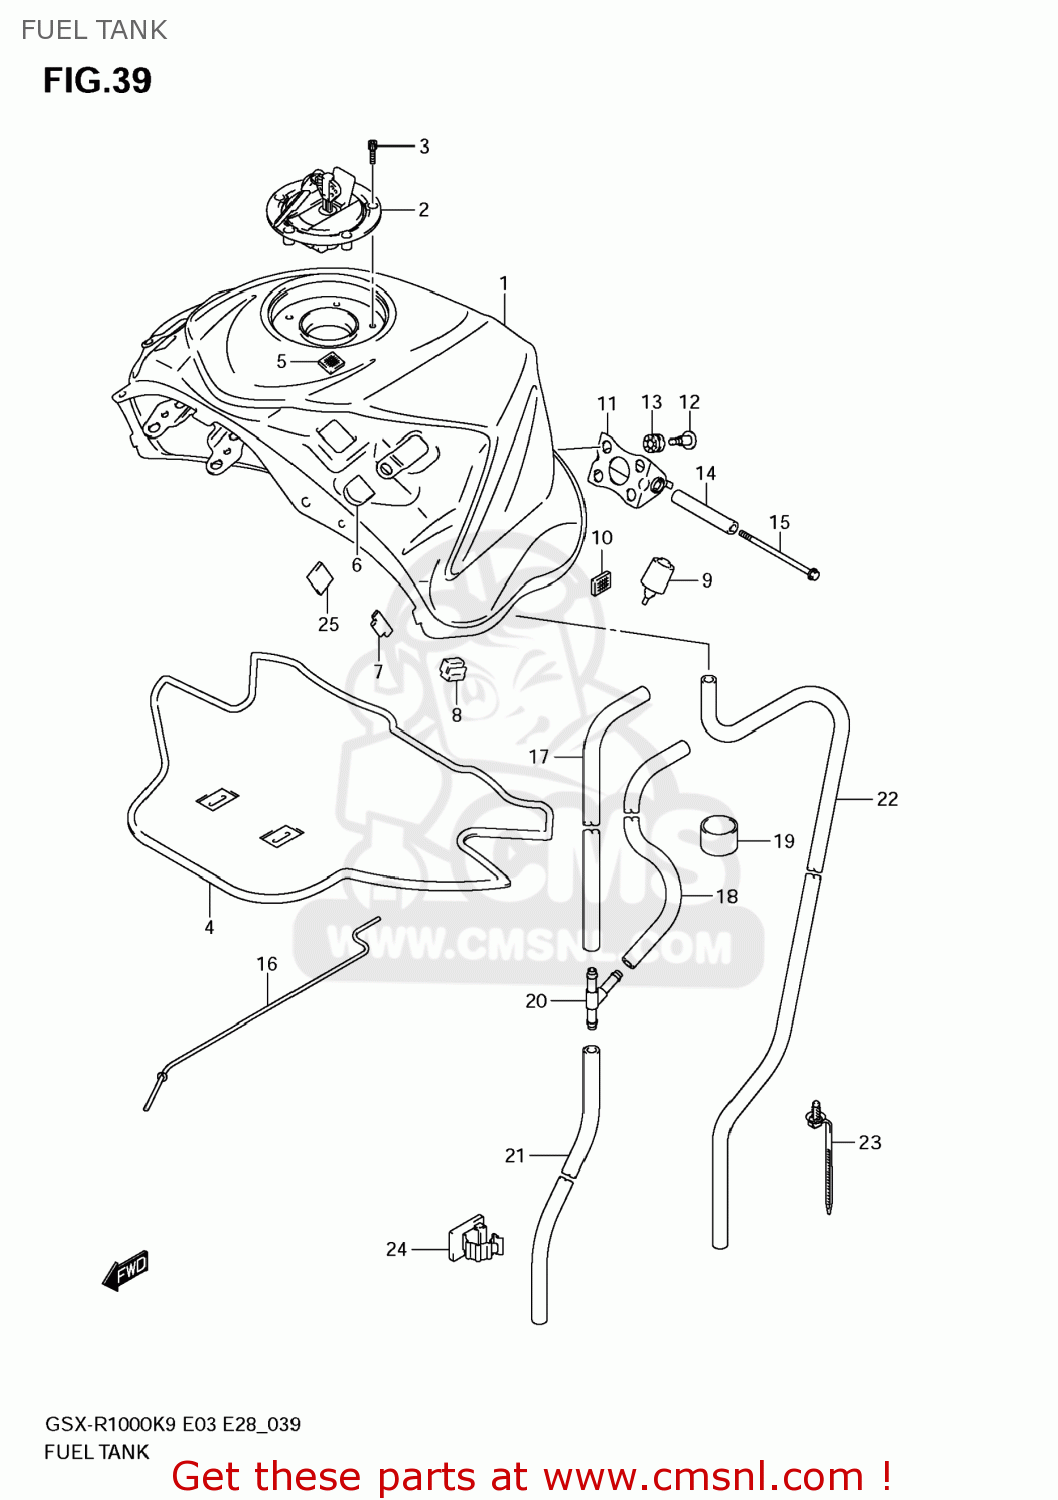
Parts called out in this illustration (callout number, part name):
1	TANK ASSY,FUEL
2	CAP SET,FUEL TANK
3	BOLT(5X20)
4	SHIELD,FUEL TANK HEAT
5	FASTENER
6	CUSHION
7	CUSHION,FUEL TANK COVER
8	CUSHION,FUEL TANK SIDE
9	CUSHION,FUEL TANK RR
10	FASTENER
11	BRACKET,FUEL TANK NO.1
12	SCREW,FUEL TAN
13	CUSHION
14	SPACER,FUEL TANK RR
15	BOLT(6X110)
16	STAY,FUEL TANK
17	HOSE,FUEL TANK BREATHER NO.1
18	HOSE,TANK BREATHER NO.2
19	HOSE(12X16X600)
20	3 WAY
21	HOSE,FUEL TANK BREATHER NO.2
22	HOSE,FUEL TANK WATER DRAIN
23	CLAMP(L:154)
24	CLAMP
25	PAD
